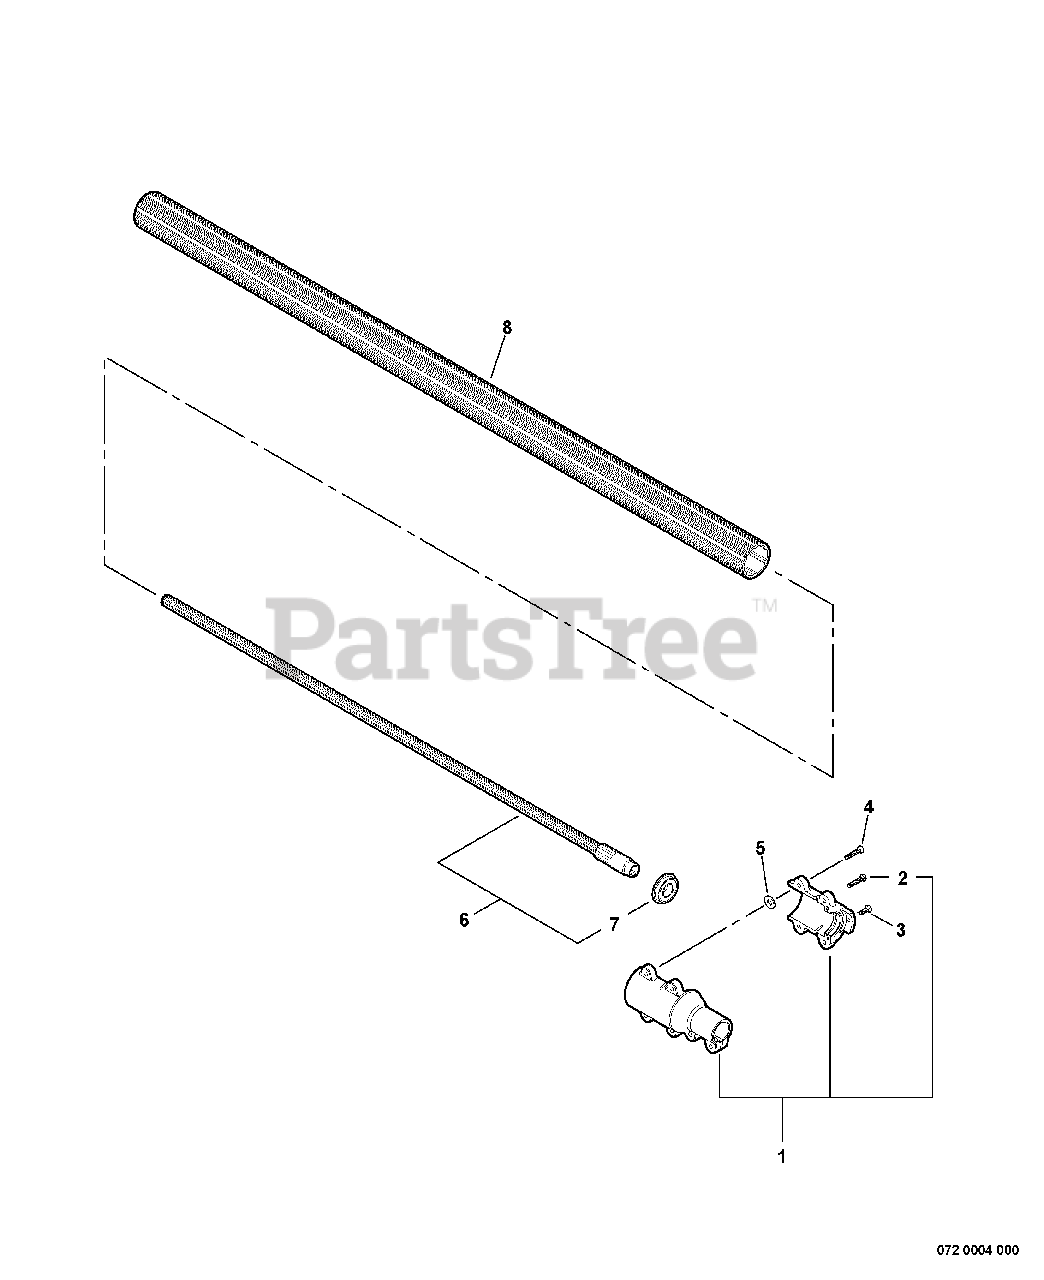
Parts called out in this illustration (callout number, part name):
1	COUPLING ASSY
2	SCREW - 5X20
3	SCREW - 5X14
4	SCREW - 5X20
5	WASHER - 5
6	DRIVESHAFT ASSY - LOWER
7	BEARING, BALL - 6002
8	PIPE, MAIN - ORANGE
